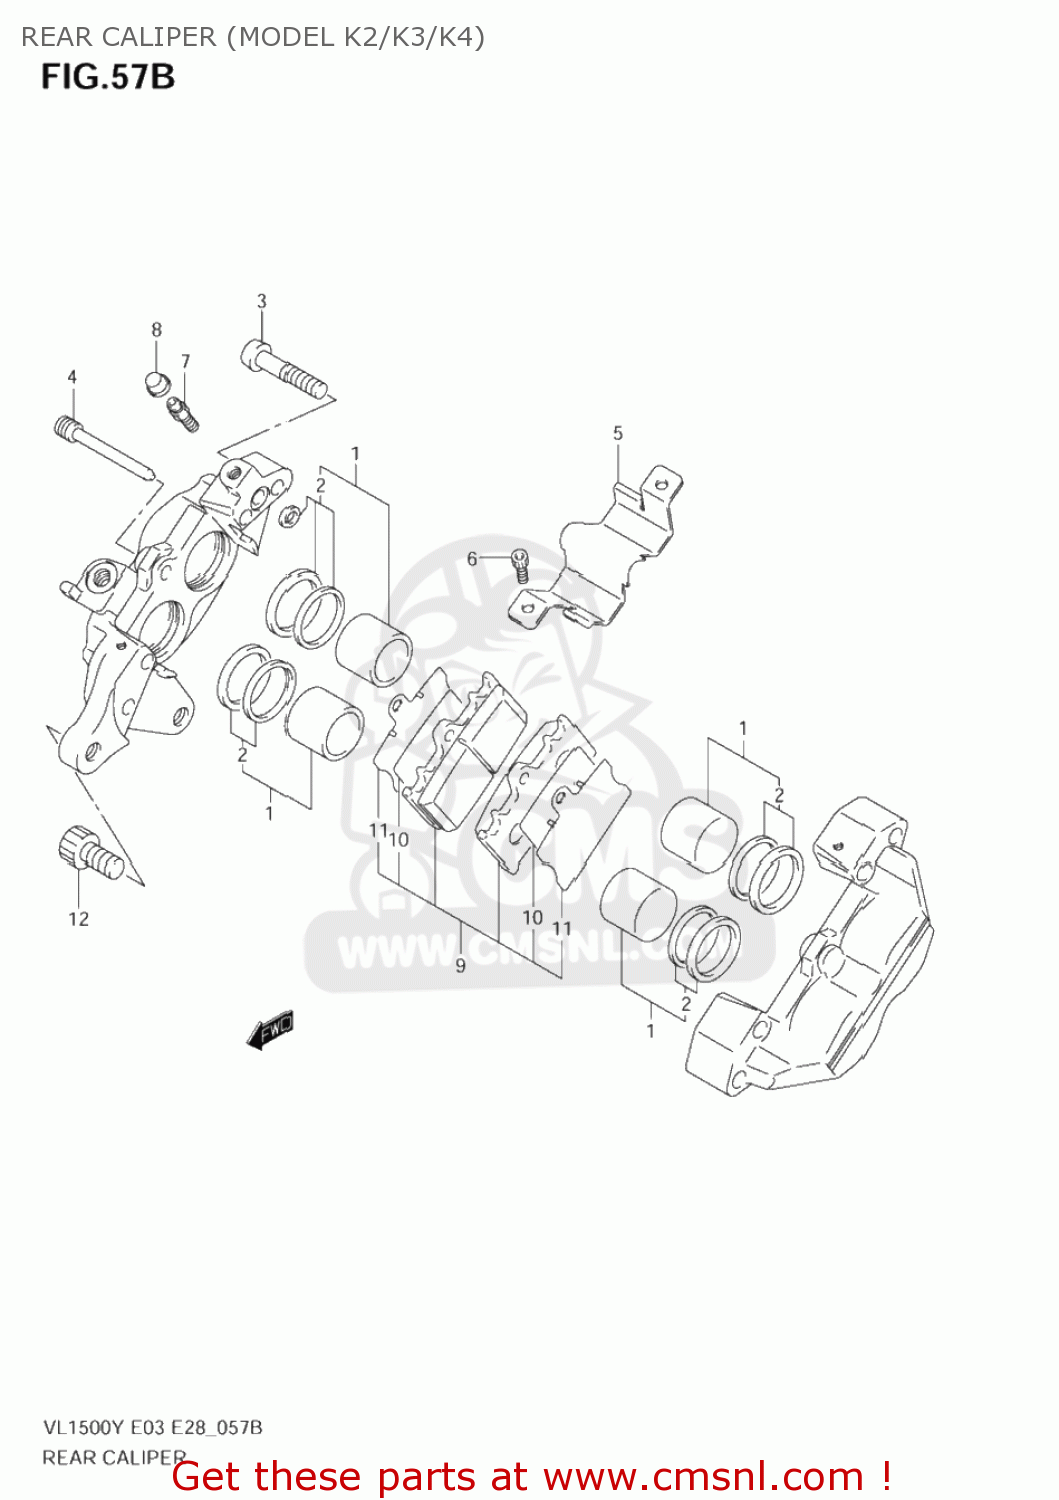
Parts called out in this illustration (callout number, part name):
1	PISTON SET
2	SEAL SET,PISTO
3	BOLT
4	PIN,PAD
5	COVER
6	SCREW
7	BLEEDER
8	CAP,BLEEDER PLUG
9	PAD & SHIM SET (NAS)
10	SHIM,PAD
11	COVER,SHIM
12	BOLT
